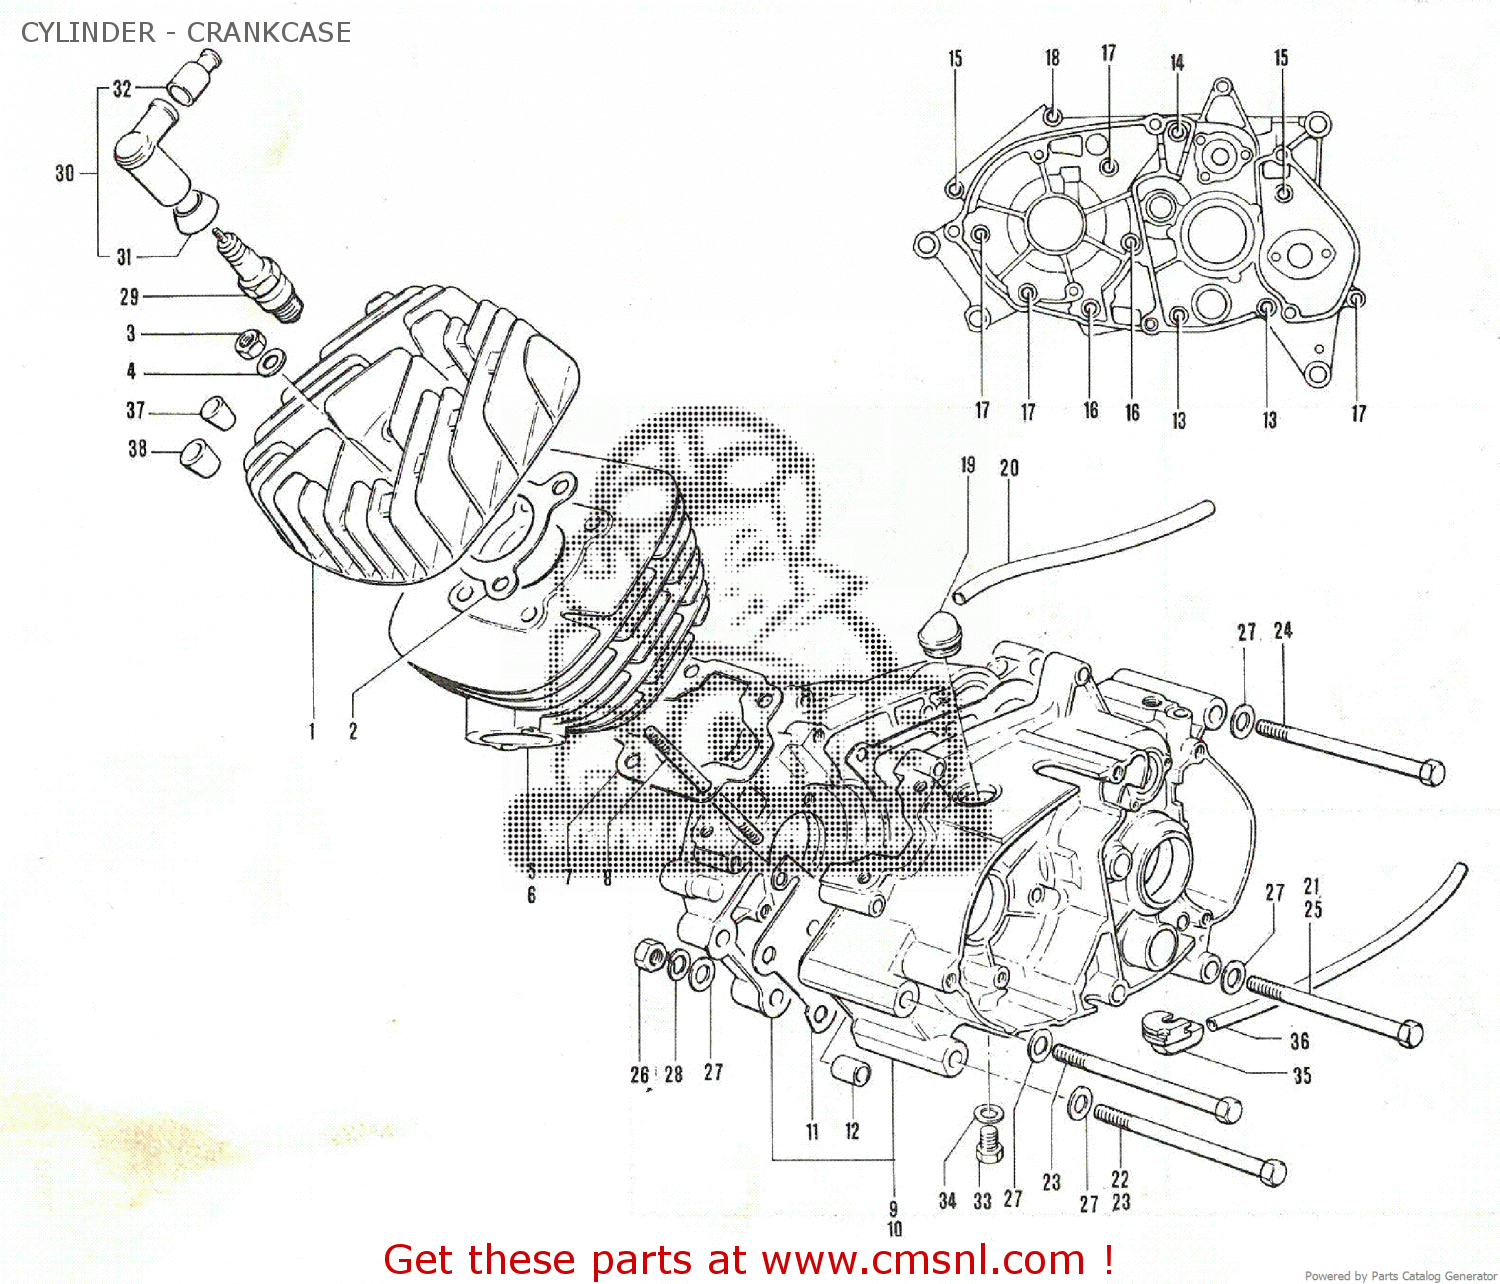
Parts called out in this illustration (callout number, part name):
1	HEAD,CYLINDER
2	GASKET,CYLINDER HEAD (NAS)
3	NUT (8MM)
4	WASHER
5	CYLINDER
7	GASKET,CYLINDER (MCA)
8	BOLT,STUD
9	CRANKCASE SET
11	GASKET,CRANKCASE (MCA)
12	PIN
13	SCREW 6X80
14	SCREW 6X70
15	SCREW
16	SCREW
17	SCREW
18	SCREW (6X35)
19	GROMMET
20	HOSE
23	BOLT
24	BOLT 10X120
25	BOLT
26	NUT
27	WASHER
28	LOCK WASHER
29	SPARK PLUG
30	CAP,SPARK PLUG
31	SEAL,SPARK PLUG
32	SPARK PLUG CAP HIGH TENSION CORD SEAL
33	PLUG
34	GASKET(10X14X3.6) (NAS)
35	GROMMET
36	HOSE
37	PAD,CYLINDER HEAD
38	PAD,CYLINDER HEAD
